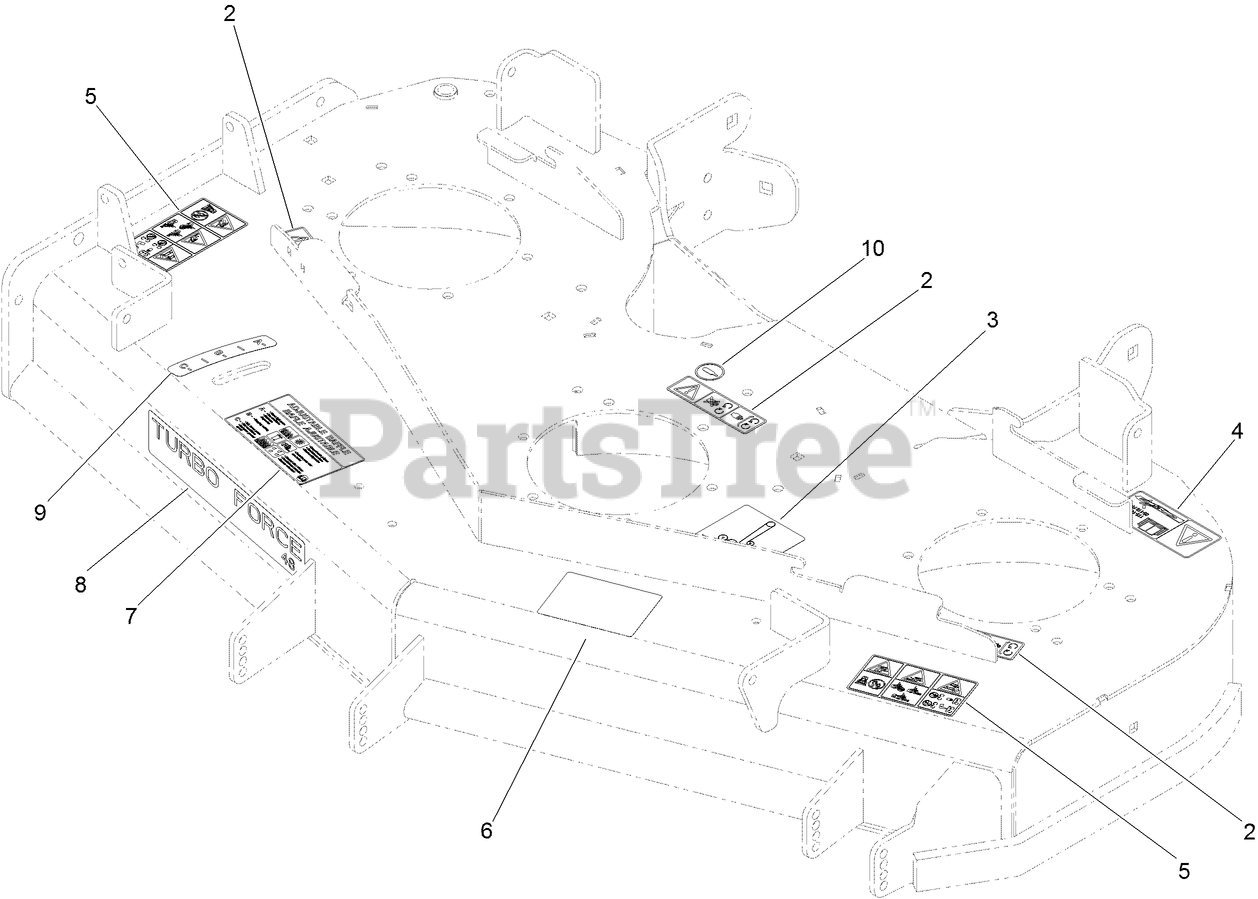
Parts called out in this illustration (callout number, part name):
2	DECAL-MISSING, COVER
3	DECAL-ROUTING, DECK BELT
4	DECAL-TORQUE, BLADE BOLT
5	DECAL-DANGER
6	DECAL-ANTI SCALP
7	DECAL-ADJUSTMENT, BAFFLE
9	DECAL-SETTING, BAFFLE
10	DECAL-GREASE
